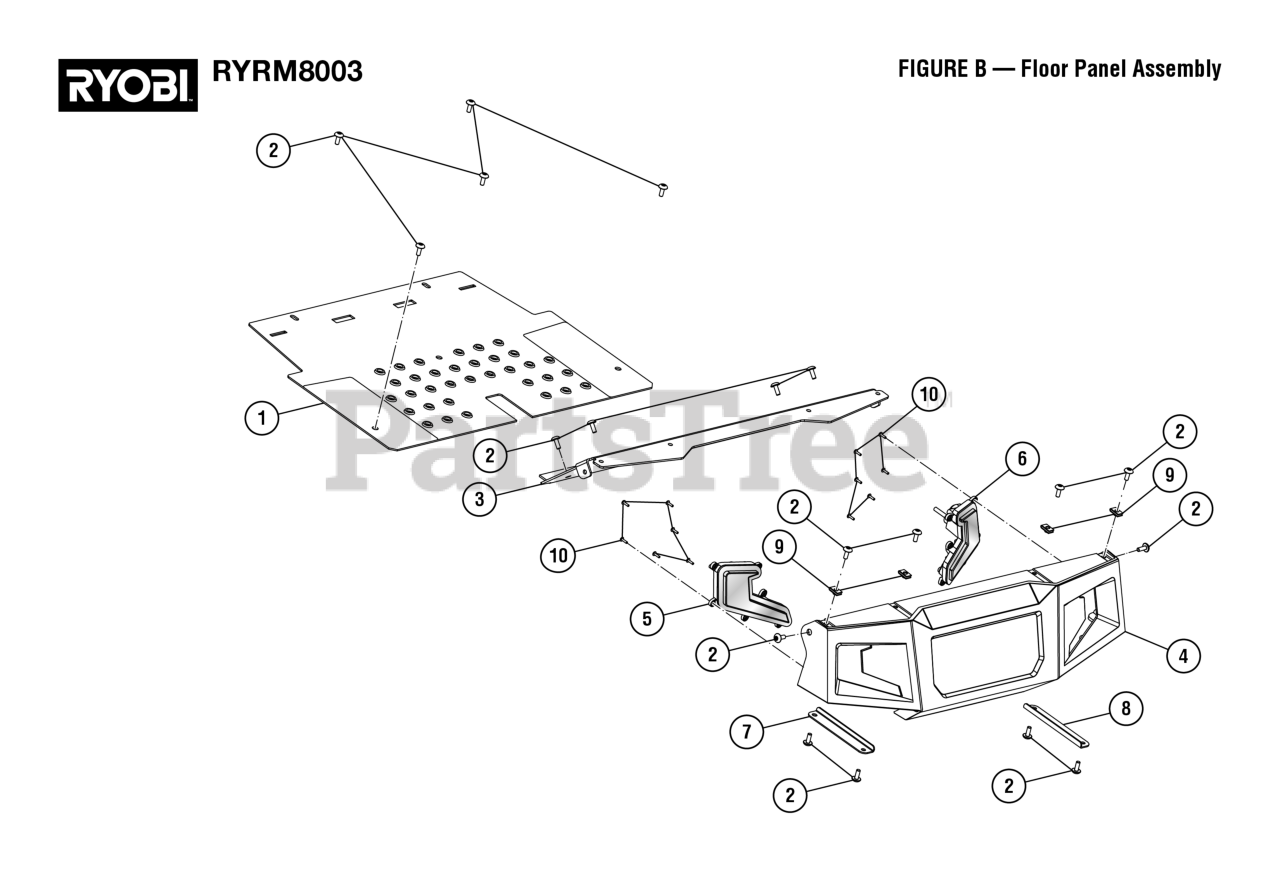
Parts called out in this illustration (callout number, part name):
1	Floor Board
2	Screw (M6 x 10 mm, Soc. Button Hd.)
3	Foot Rest
4	Front Fascia
5	LED Headlight Assemly (Right)
6	LED Headlight Assembly (Left)
7	Fascia Brace (Right)
8	Fascia Brace (Left)
9	Clip-On Nut (M6)
10	Screw (M3 x 12 mm, Pan Hd.)
